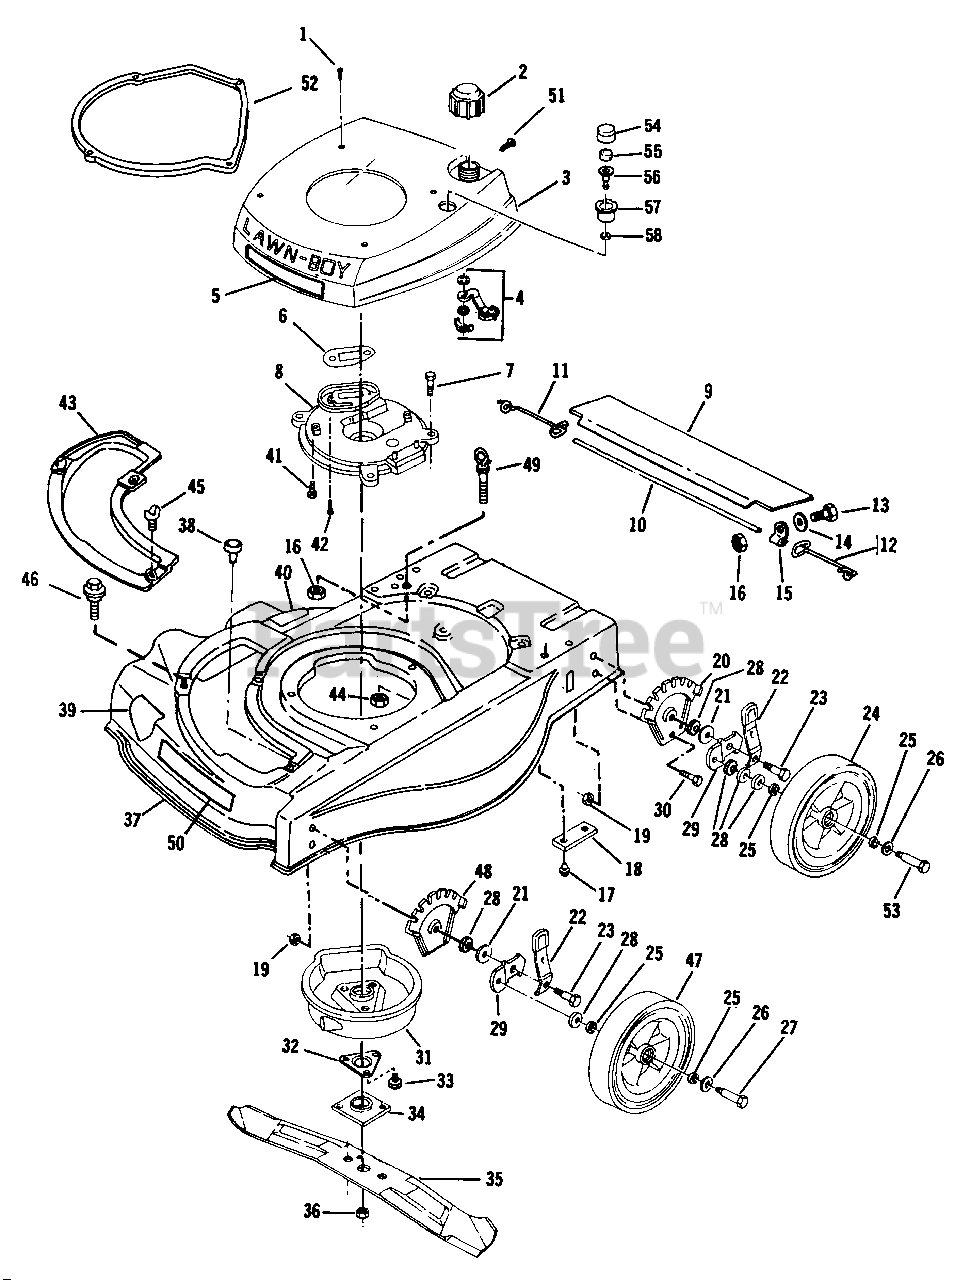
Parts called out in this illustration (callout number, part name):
1	Screw
2	Fuel Cap Assembly
3	Shroud Assembly
4	Fuel Shut-Off Assembly
5	Decal-Special
6	Gasket
7	Screw-Muffler Plate to Housing
8	Plate-Muffler
9	Shield-Trailing
10	Rod-Trailing Shield
11	Spring-R.H.
12	Spring-L.H.
13	Screw-Trailing Shield
14	Washer-Trailing Shield
15	Clamp-Trailing Shield
16	Nut-Trail. Shield and Eyebolt
17	Screw-Handle Bracket
18	Plate-Handle Bracket to Housing
19	Nut-Hgt. Adj. and Back-up Plate
20	Plate-Height Adjust-Rear
21	Washer-Wheel Mounting Brk't.
22	Knob and Spring Assembly
23	Bolt-Wheel Brk't. to Knob and Spring Assembly
24	Wheel-Rear
25	Washer-Felt
26	Washer-Wheel Bolt Head
27	Bolt-Shoulder, Wheel-Front
28	Washer
29	Bracket-Wheel Hgt. Adj.
30	Screw-Hgt. Adj. Plate
31	Muffler Cover Assembly
32	Support-Crankshaft
33	Screw-Crankshaft Support
34	Collar and Plate Assembly
35	Blade-21"
36	Nut
37	Housing-Assembly
38	Grommet
39	Decal-Blade Contact Warning
40	Decal-Discharge Area
41	Screw-Muffler Plate to Block
42	Screw-Muffler Plate to Block
43	Cover Plate
44	Nut-Muffler Plate to Housing
45	Wing Screw
46	Screw-Plate and Chute Mtg.
47	Wheel-Front
48	Plate-Height Adj.-Front
49	Eyebolt
50	Decal-Manual Start
51	Screw-Shroud to C.D. Brk't.
52	Spacer-Shroud to Base
53	Bolt-Shoulder, Wheel-Rear
54	Primer Bulb
55	Filter
56	Base Primer
57	Cup Primer
58	Locknut
